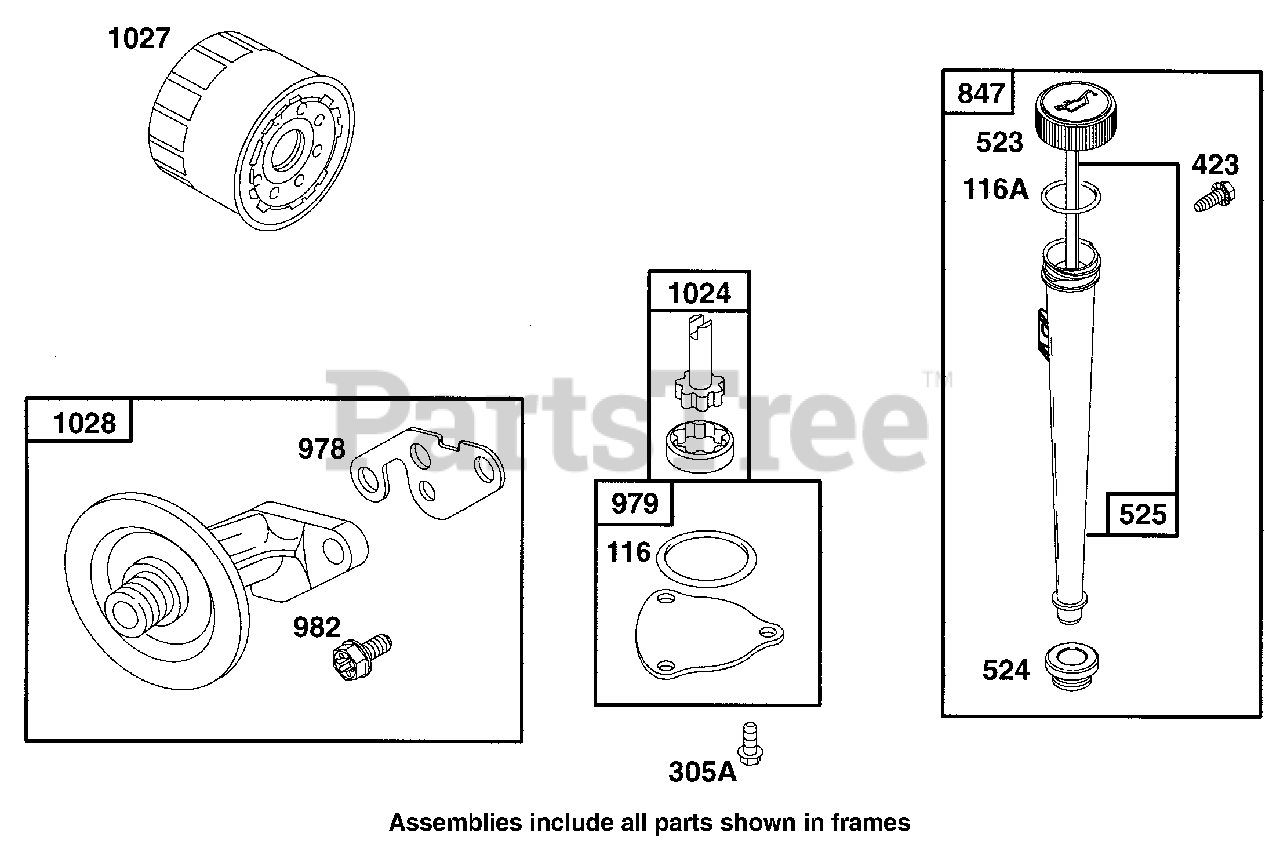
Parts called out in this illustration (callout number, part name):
116	Seal-O-Ring
116A	Seal-O-Ring
305A	Hex Screw
423	Shoulder Screw
523	Dipstick
524	Fill Tube Seal
525	Oil Fill Tube
847	Dipstick/Tube Assembly
978	Oil Adapter Gasket
979	Pump Cover
982	Hex Screw
1027	Oil Filter
1028	Filter Adapter
